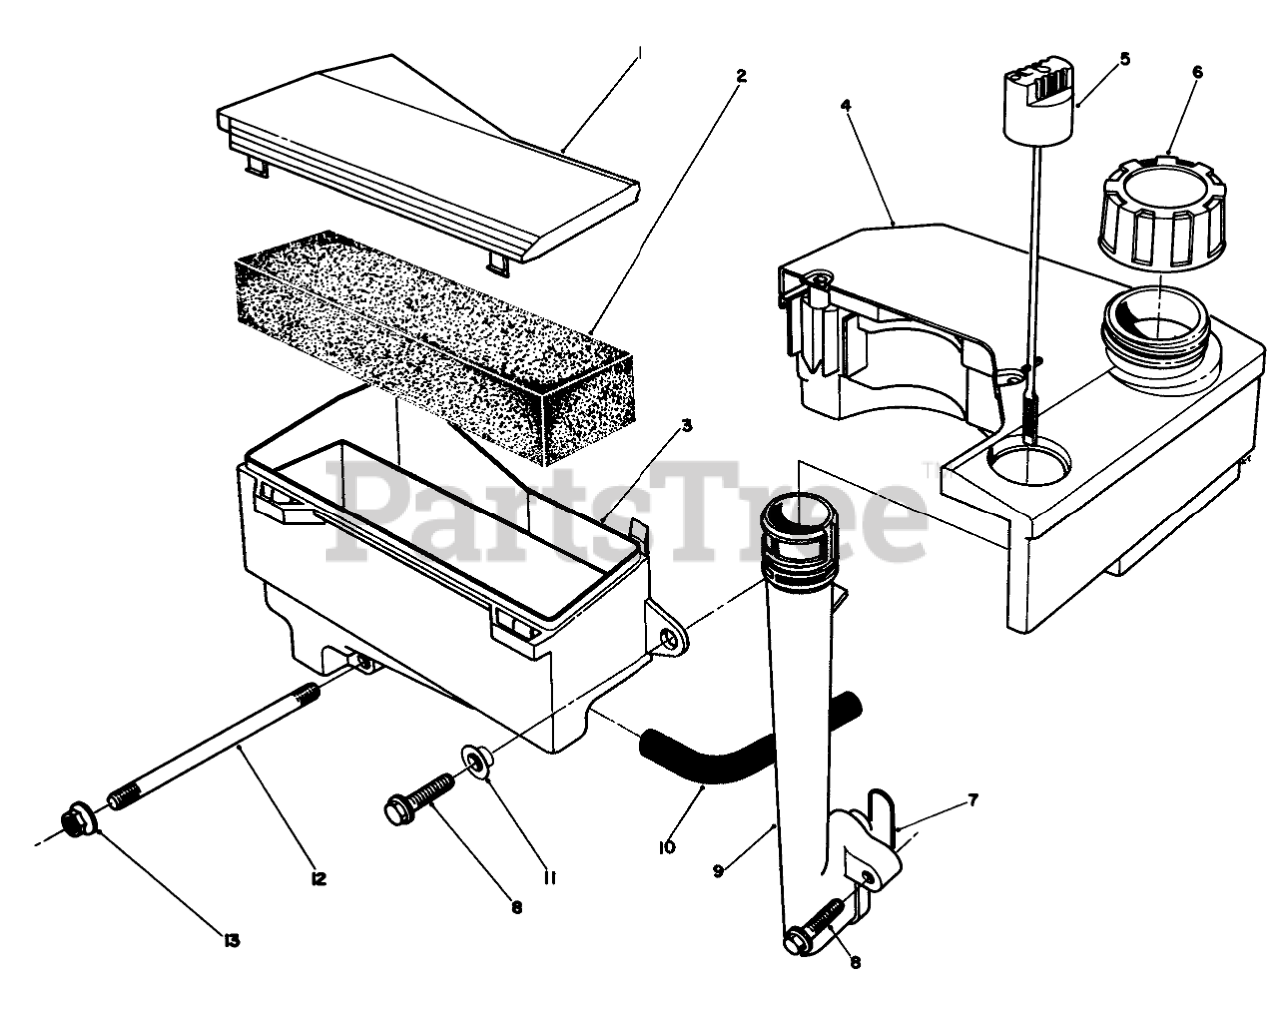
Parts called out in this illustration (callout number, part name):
1	Cover-Air Cleaner
2	Filter-Foam
3	Body-Air Cleaner
4	TANK ASM
5	Dipstick-Oil
6	GAS CAP ASM
7	0-Ring-Oil Tube
9	Tube-Oil Fill
11	SPACER
12	Stud-Carburetor
